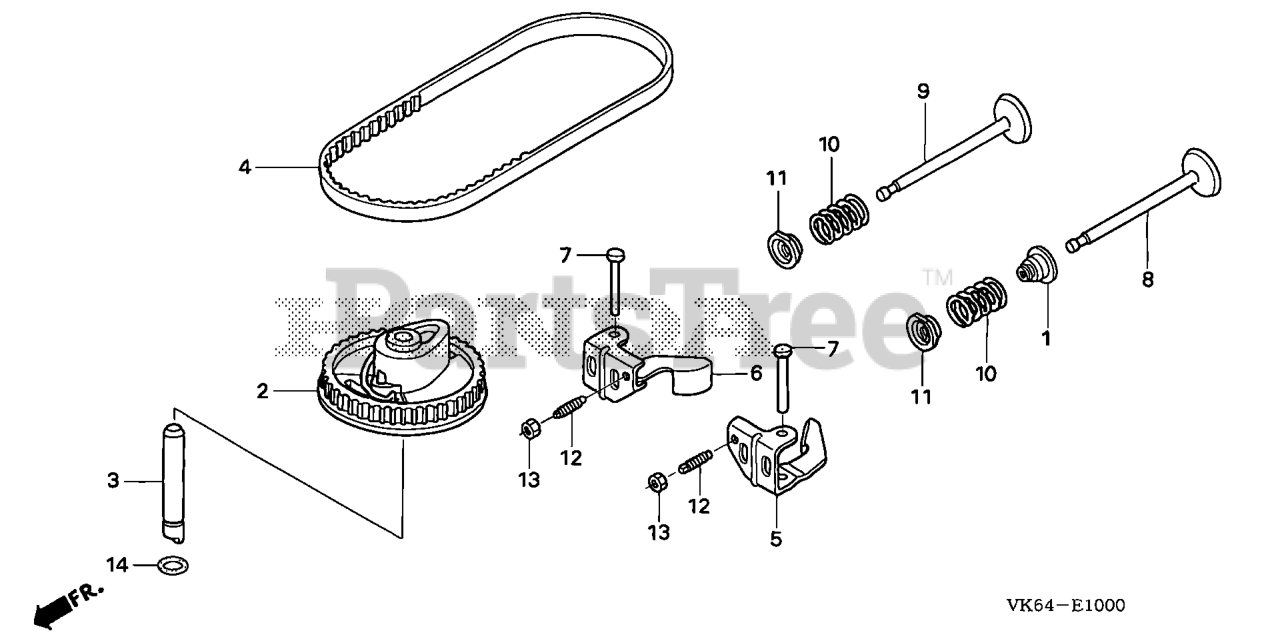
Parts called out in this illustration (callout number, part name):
1	SEAL, VALVE STEM
2	PULLEY, CAMSHAFT
3	SHAFT, CAM PULLEY
4	BELT, TIMING (84HU7 G-200)
4	BELT, TIMING (84HU6 G-200)
5	ARM, IN. VALVE ROCKER
6	ARM, EX. VALVE ROCKER
7	SHAFT, ROCKER ARM
8	VALVE, IN. (TECHNOSTAR)
9	VALVE, EX. (L8E)
9	VALVE, EX. (C8E)
10	SPRING, VALVE
11	RETAINER, VALVE SPRING
12	SCREW, TAPPET ADJ.
13	NUT, TAPPET ADJ.
14	O-RING (6.8X1.9) (ARAI)
